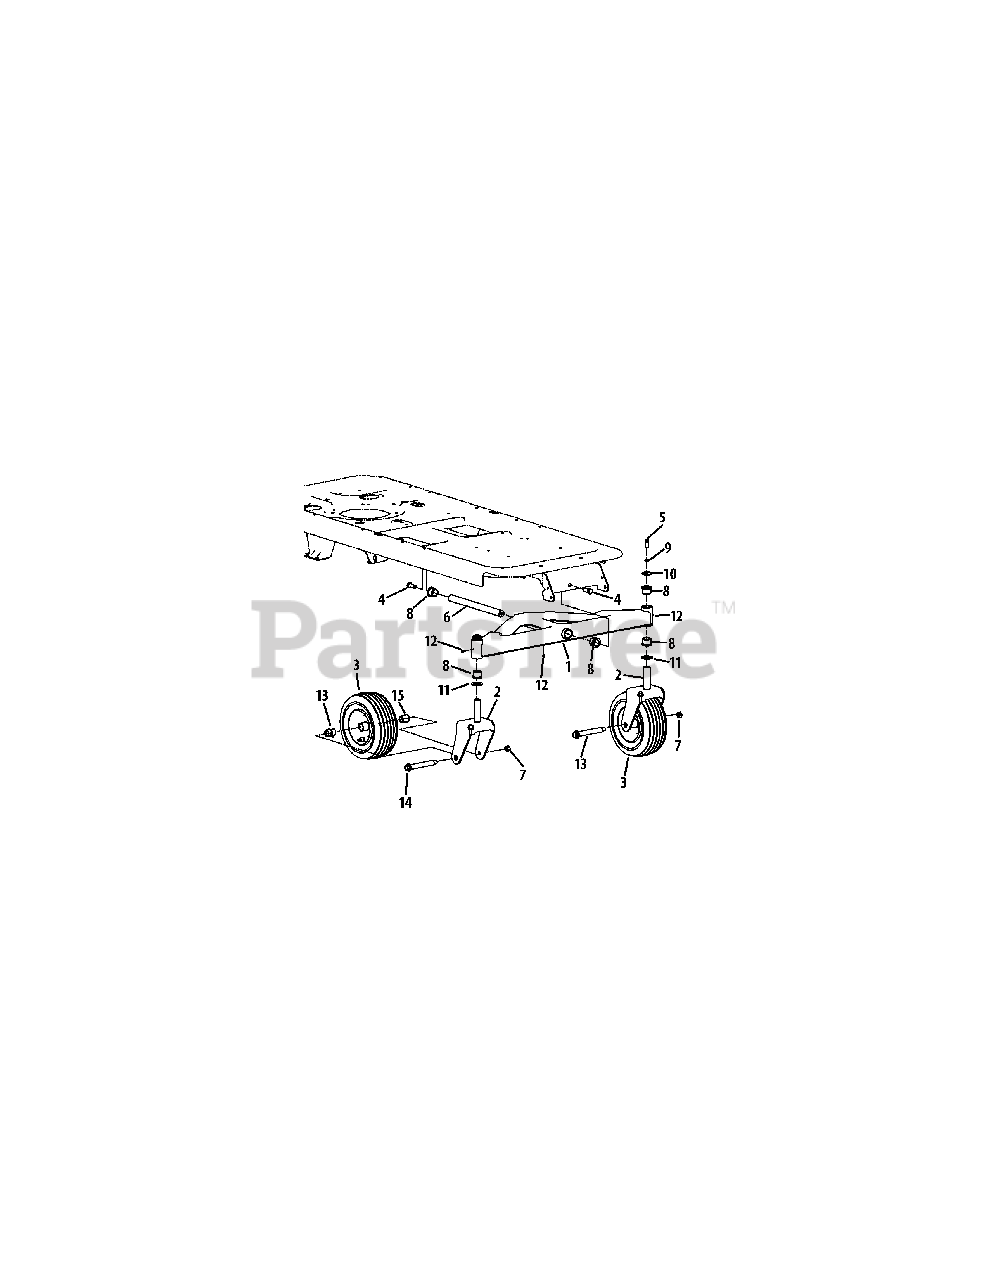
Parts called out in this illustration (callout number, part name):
1	Front Pivot Axle
2	Castor Wheel Bracket
3	Wheel Assembly, 11.0 x 4.0 x 5.0
4	Hex Lock Screw, 1/2-13 x 1.25
5	Hex Cap Screw, 3/8-16 x 1.0
6	Axle Shaft
7	Hex Lock Nut, 1/2-13
8	Flange Bearing, 1.0 x 1.246
9	Lock Washer, 3/8
10	Flat Washer, .39 x 1.5 x .134
11	Flat Washer, 1.0 x 1.75 x .107
12	Lube Fitting, 3/16 Drive
13	Shoulder Screw, .75 x 4.75 x 7/16-14
14	Flange Bearing, .76 x 1.0 x 1.2
15	Flange Bearing, .76 ID w/ Lube Ftg.
